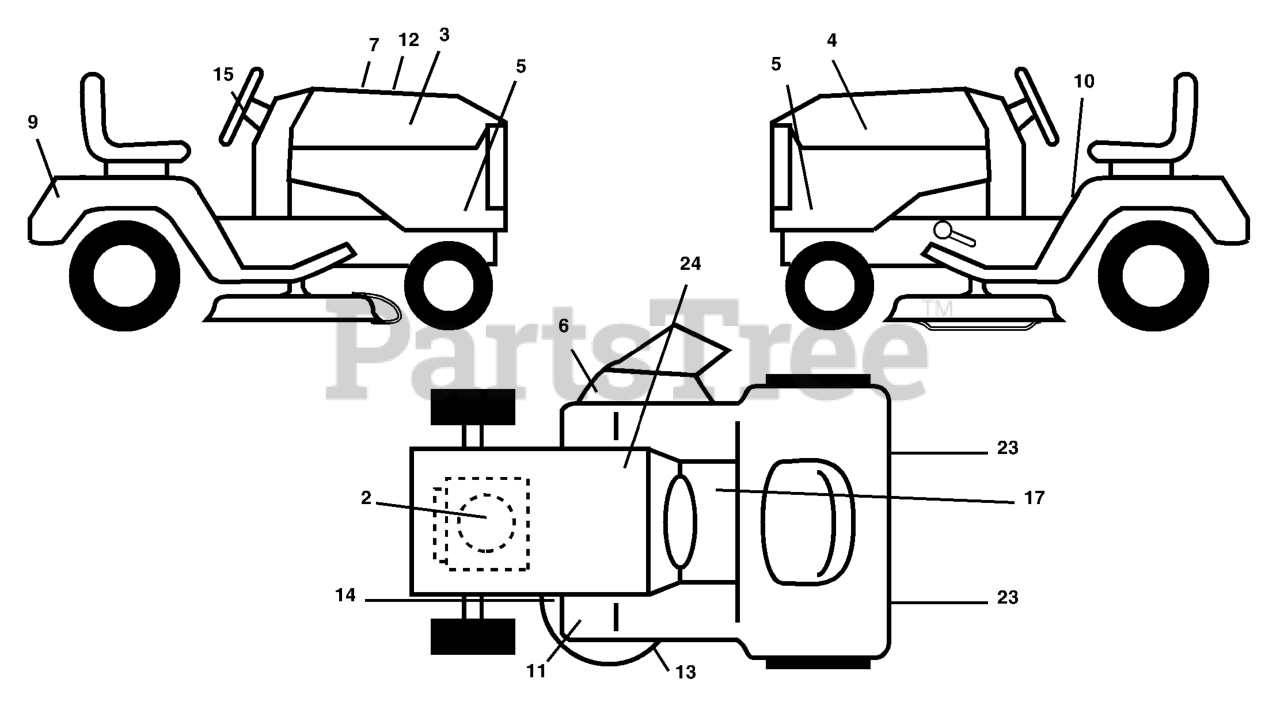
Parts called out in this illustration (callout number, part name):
1	DECAL, MOWER HEAVY DUTY
5	SIDE PANEL DECAL
6	DECAL.WARN.KEEP.HAND.AWAY
7	DECAL HOOD CUST. RESP.
9	DECAL, FENDER
10	DECAL FENDER DANGER
11	DECAL, FOOTREST
13	DECAL.SCHEMATIC.DECK
14	DECAL CLUTCH/BRAKE
15	DECAL.STEERING.HUSQ.BLUE
17	DECAL, SADDLE BRAKE PARKING
23	REFLECTOR-TAIL YT
24	DECAL BTRY SYMBOLS
